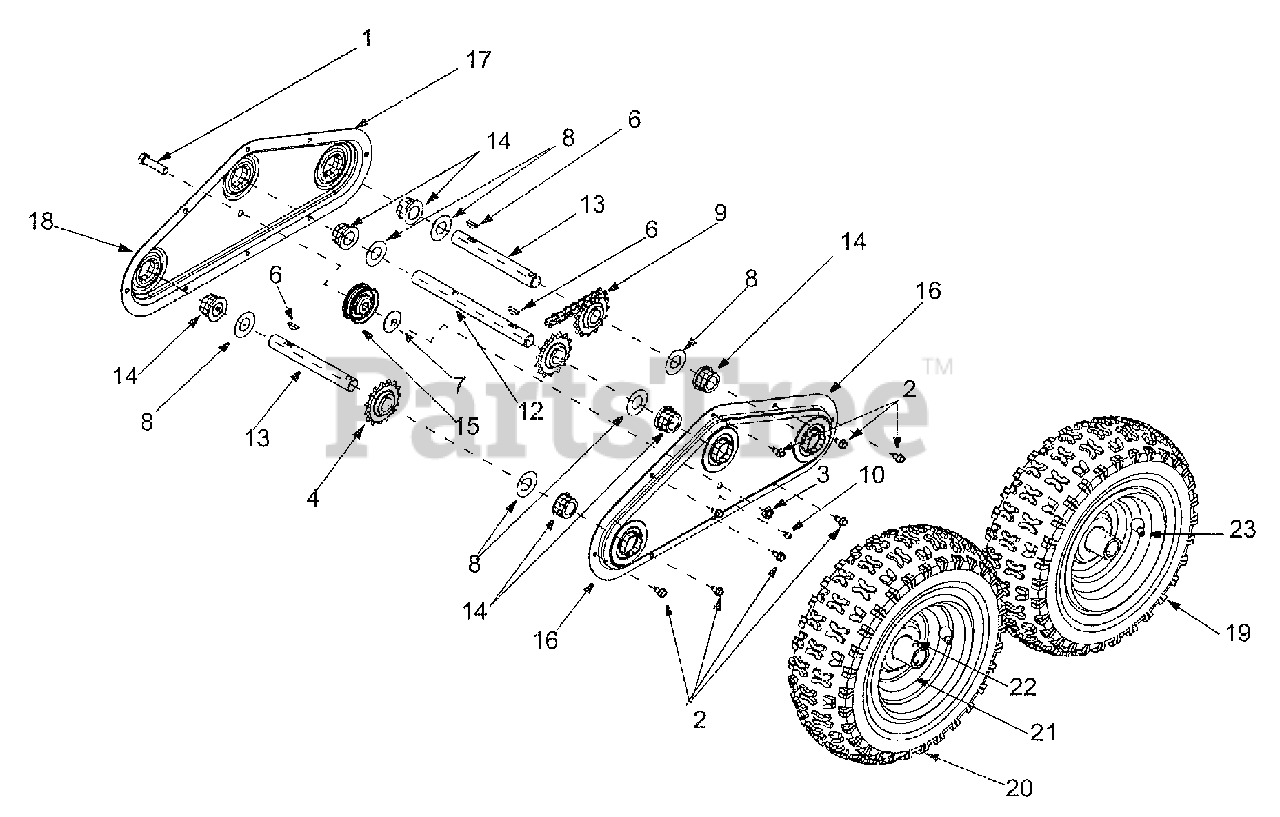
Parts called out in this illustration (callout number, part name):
1	Special Hex Screw: 3/8-24 x 1.5"
2	TT Screw: 1/4-20 x 0.5"
6	Key
7	Flat Washer
9	Lubricant: 6 in 1
10	Lube Fitting
14	Hex Flange Bearing
23	Air Valve
